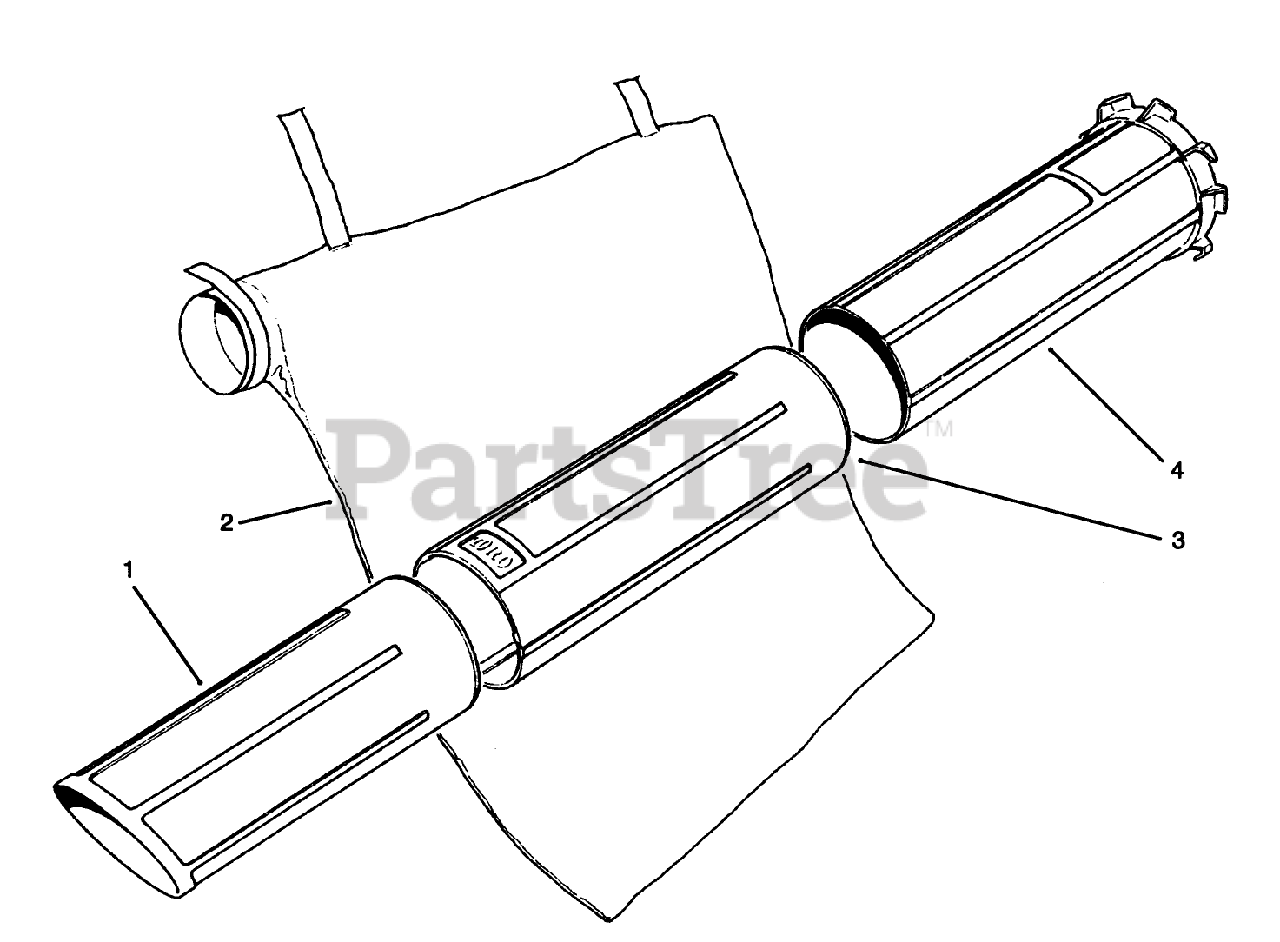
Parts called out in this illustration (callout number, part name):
1	LOWER VAC TUBE
2	VACUUM BAG
3	MIDDLE VAC TUBE
4	UPPER VAC TUBE
